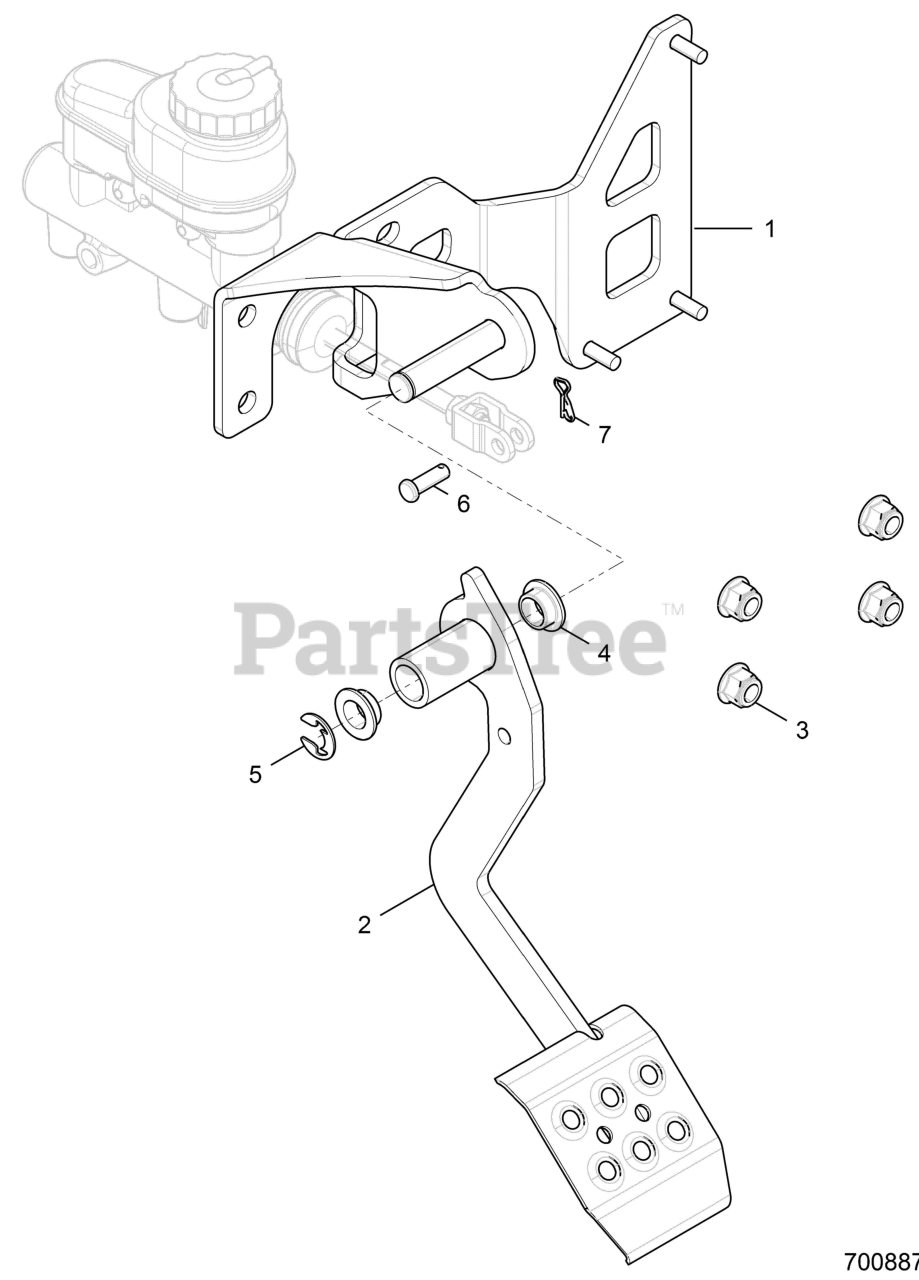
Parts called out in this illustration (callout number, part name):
1	WELD-PEDAL MOUNT,BLK
2	WELD-BRAKE PEDAL,MATTE'BLK
3	NUT-M8X1.25,FLG,NYLOC-OLIVE D
4	BUSHING-PEDAL PIVOT
6	PIN-CLEVIS, 1/4 X 3/4 -Y
7	PIN-CLIP,14MM
